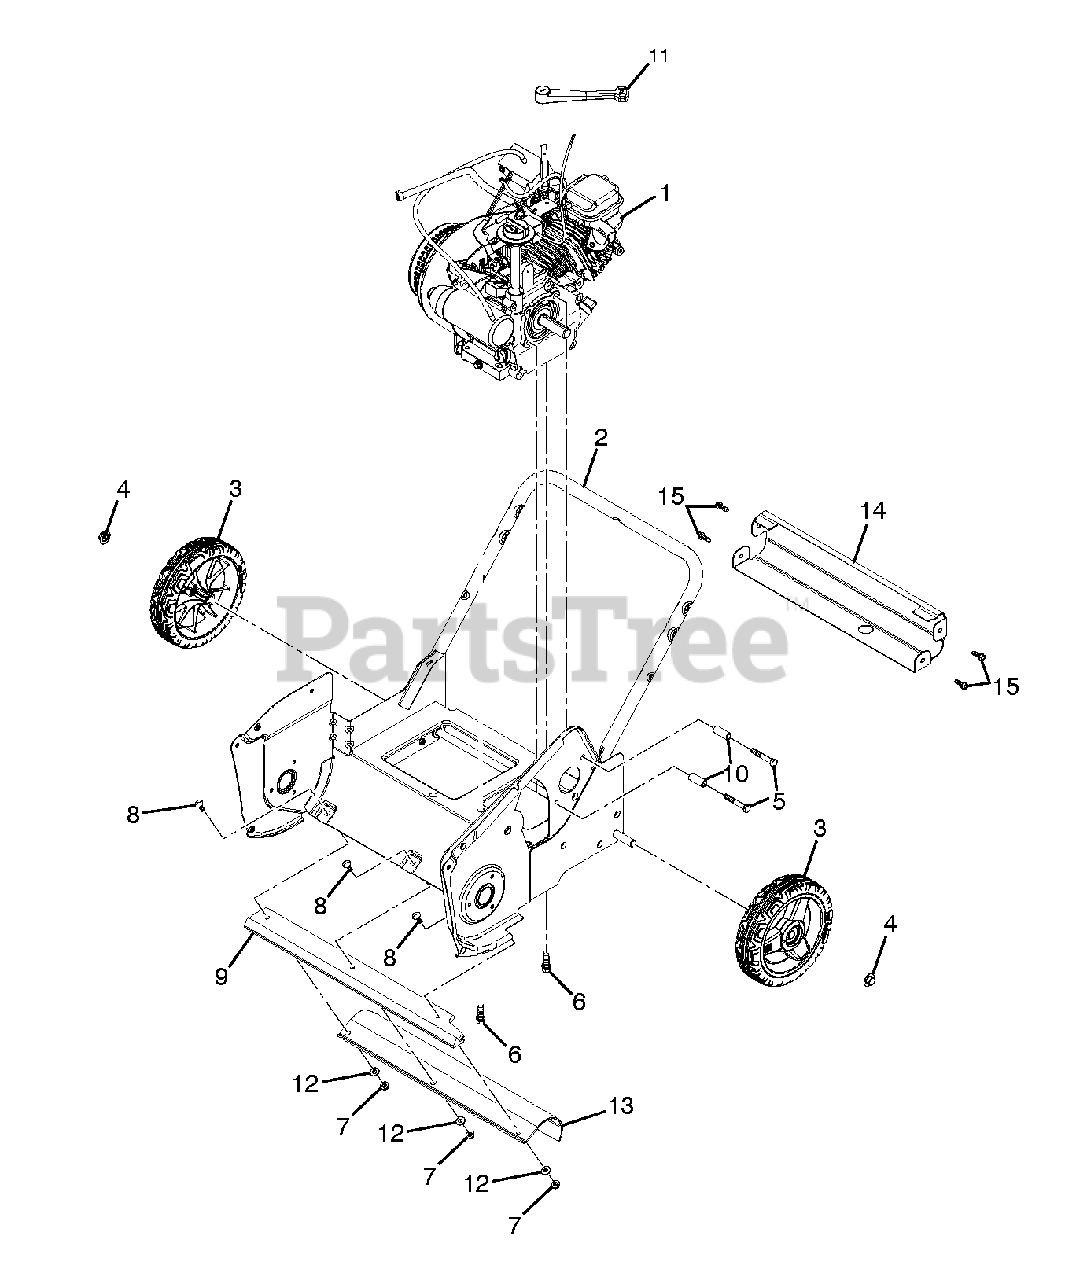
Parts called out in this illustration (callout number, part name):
1	ENGINE.LCT.208CC.ESTART.W/ALT
2	FRAME.WELDMENT.GREY
3	WHEEL.8".GRAY.HUSQ.BUSHING.CEN
4	NUT.PUSH.AXLE.0.5IN
5	SCREW. 5/16-24 X 2.00"HHCS
6	BOLT 3/8-16X1-1/8
7	NUT.HEX.FLANGE.1/4
8	BOLT.CARRIAGE.1/4-20 X 7/8
9	BAR.SCRAPER
10	SPACER.ENGINE
11	LEVER.CHOKE
13	SKIRT.SCRAPPER-SSST
14	SUPPORT.SSST.REAR.FRAME.GREY
15	SCREW.PAN.HD.TORX.1/4-20X.750
